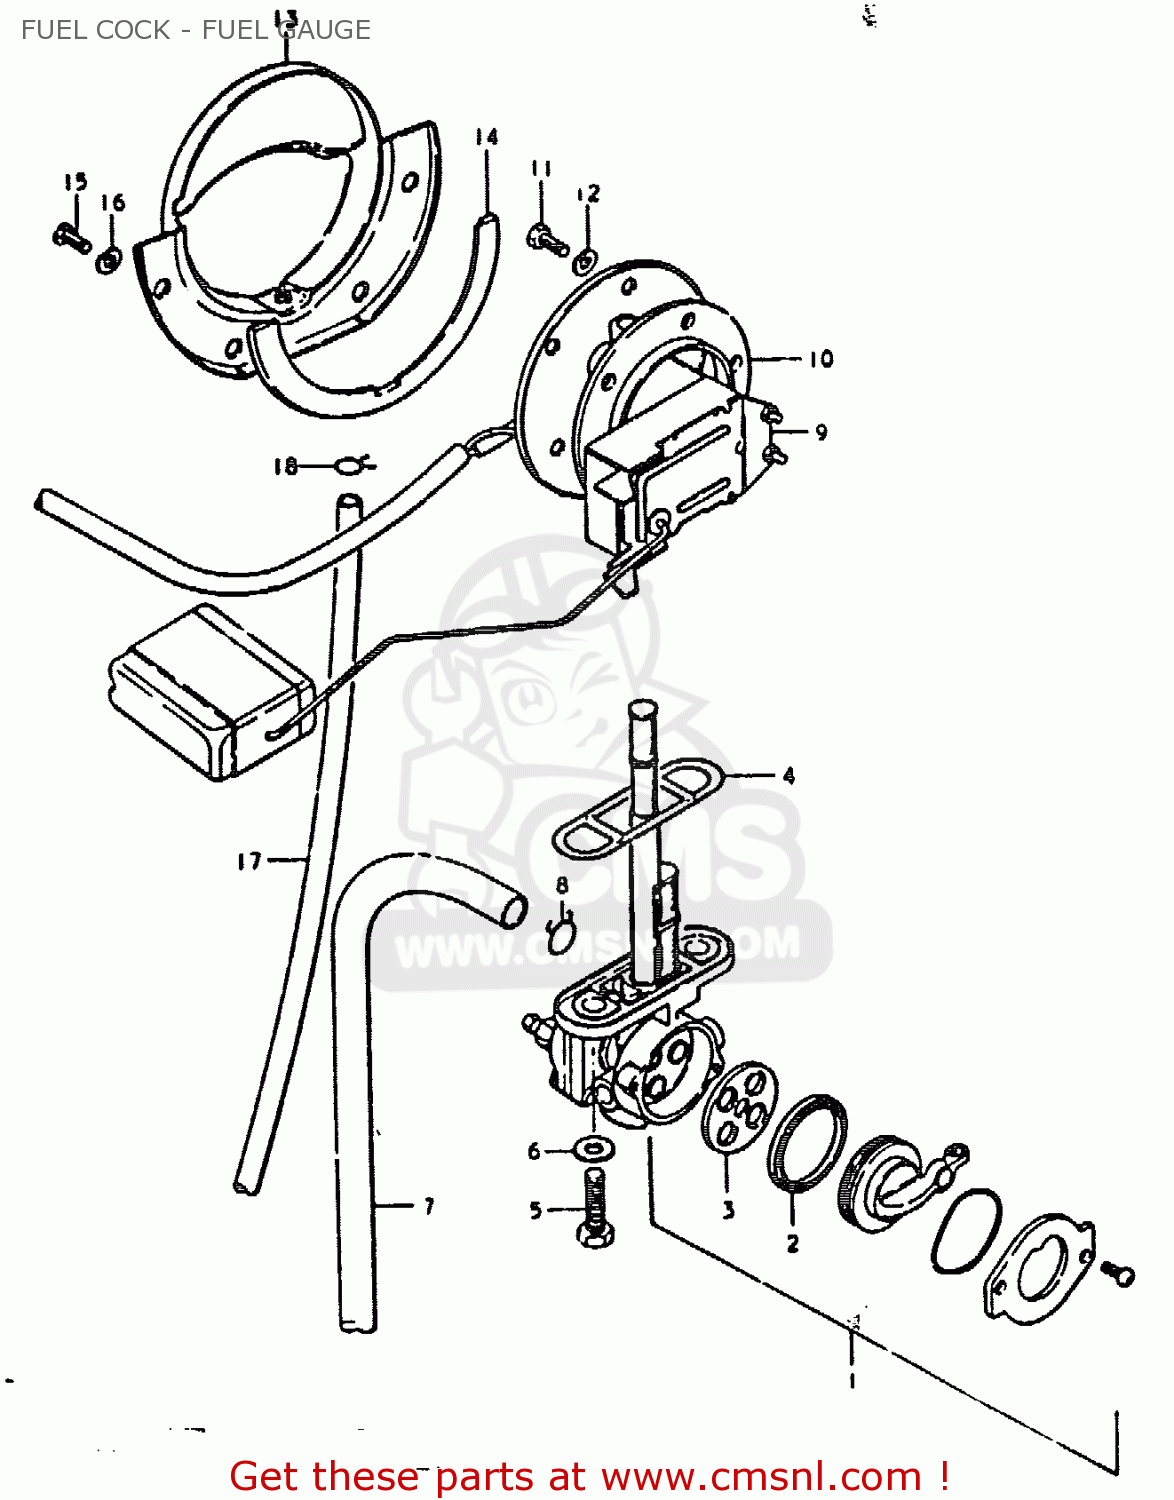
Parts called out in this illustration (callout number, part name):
1	COCK ASSY,FUEL
2	V SEAL,FUEL COCK
3	GASKET (NAS)
4	GASKET, FUEL COCK (NAS)
5	SCREW(6X20)
6	GASKET
7	HOSE
8	CLIP
9	GAUGE ASSEMBLY,FUEL LEVEL
10	GASKET,FUEL LEVEL GAUGE (NAS)
11	BOLT
12	LOCK WASHER
13	PLATE,FUEL DRAIN
14	GASKET,FUEL DRAIN PLATE (NAS)
15	SCREW
16	LOCK WASHER
17	HOSE
18	CLIP
